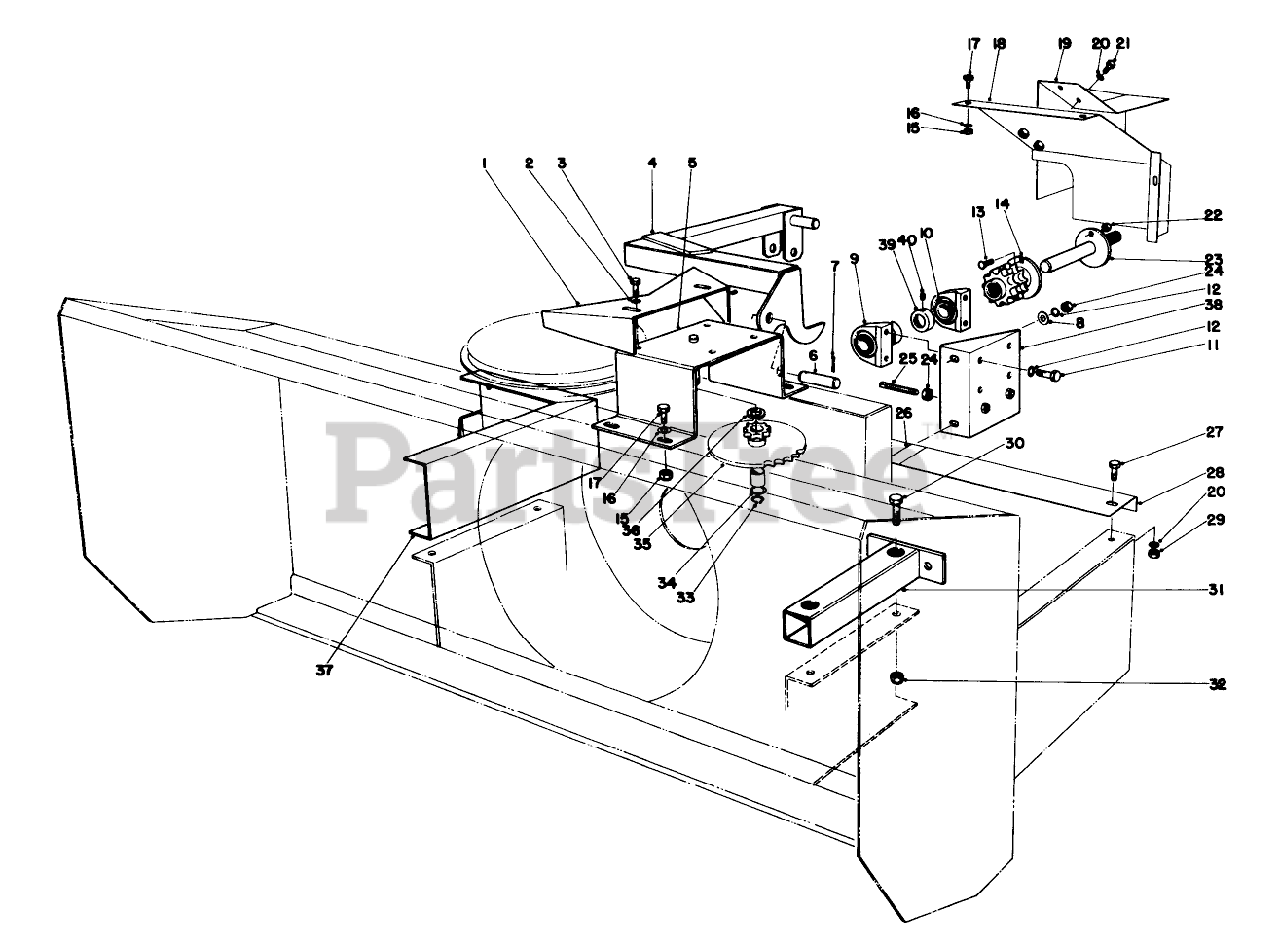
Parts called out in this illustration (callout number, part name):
1	Chain Shield
2	WASHER-LOCK
3	SCREW-HH
4	Lift Arm Assembly
5	Chute Rotator
6	Upper Lift Pin
7	PIN-COTTER
8	Washer
9	Cast Bearing Housing
10	BEARING
11	SCREW-HH
12	WASHER-LOCK
13	SCREW-HH
14	Shear Plate & Sprocket
15	NUT-LOCK, SIDE
16	WASHER-FLAT
17	SCREW-HH
18	Shield
19	P.T.O. Shield
20	WASHER-LOCK
21	SCREW-HH
22	NUT-LOCK, NI
23	Countershaft
24	NUT-HEX
25	Set Screw Sq. Hd.
26	Decal
27	SCREW-HH
28	Shield Cross Shaft
29	NUT-HEX
30	Capscrew
31	Left Hand Mounting Bracket
32	NUT-HEX
33	RING-SNAP, EXTERNAL
34	Washer
35	Idler and Bearing
36	SPACER
37	Right Hand Mounting Bracket
38	Bearing Mount
39	COLLAR-LOCK, BEARING
40	SCREW-SET, HSH
